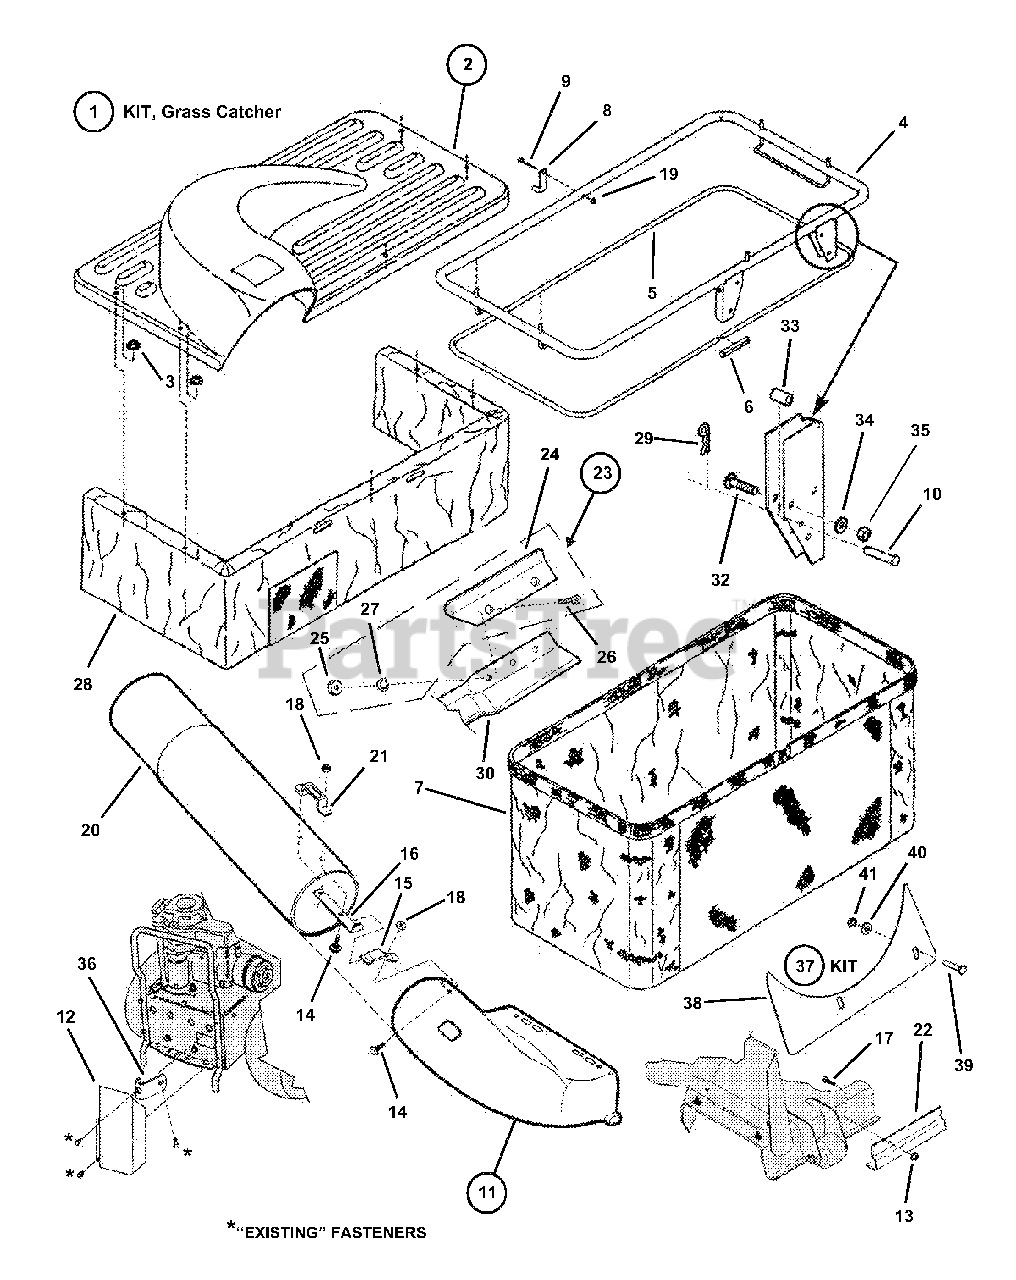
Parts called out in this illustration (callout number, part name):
1	KIT, Grass Catcher (42" Models)
2	TOP, Container
3	WASHER, 5/16" Faceted
4	FRAME, Weldment
5	ROD, Bag
6	CONNECTOR, Bag Rod
7	BAG, Grass
8	LATCH, Top
9	SCREW, #10-32 x 1-3/8" Hex Head Machine
10	PIN, 5/16 x 1-11/16" Clevis
11	ADAPTER, Deck
12	SHIELD, Muffler Heat (8 HP Engines)
13	NUT, 5/16-18 Hex Flange Lock, Grade 5
14	BOLT, 1/4-20 x 5/8" Flat Head Square Neck, Grade 2
15	LATCH, Tube
16	BASE, Handle
17	SCREW, 5/16-18 x 3/4" Pan Head Machine
18	NUT, 1/4-20 Hex Flange Lock, Grade 5
19	NUT, #10-32 Hex Nyloc
20	TUBE, Grass (39" long)
21	HANDLE, Tube
22	BAFFLE, 42" Deck
23	KIT, Air Lift
24	EXTENSION, Air Lift
25	NUT, 5/16-24 Hex
26	SCREW, 5/16-24 Oval Head Machine
27	WASHER, 5/16" Internal Tooth Lock
28	DUST SKIRT
29	PIN, 3/32 x 1-1/2" Hair
30	BLADE, 21" Air Lift
32	BOLT, 5/16-18 x 1-1/2" Square Neck Carriage, Grade 5
33	PAD, Bumper Mount
34	WASHER, 5/16" Flat
35	NUT, 5/16-18 Hex Center Lock, Grade B or 5
36	REINFORCEMENT, Bumper
37	KIT, Catcher Debris Shield
38	SHIELD, Debris
39	BOLT, 1/4-20 x 1-1/2" Hex
40	WASHER, 1/4" Flat
41	NUT, 1/4-20 Hex Top Lock
